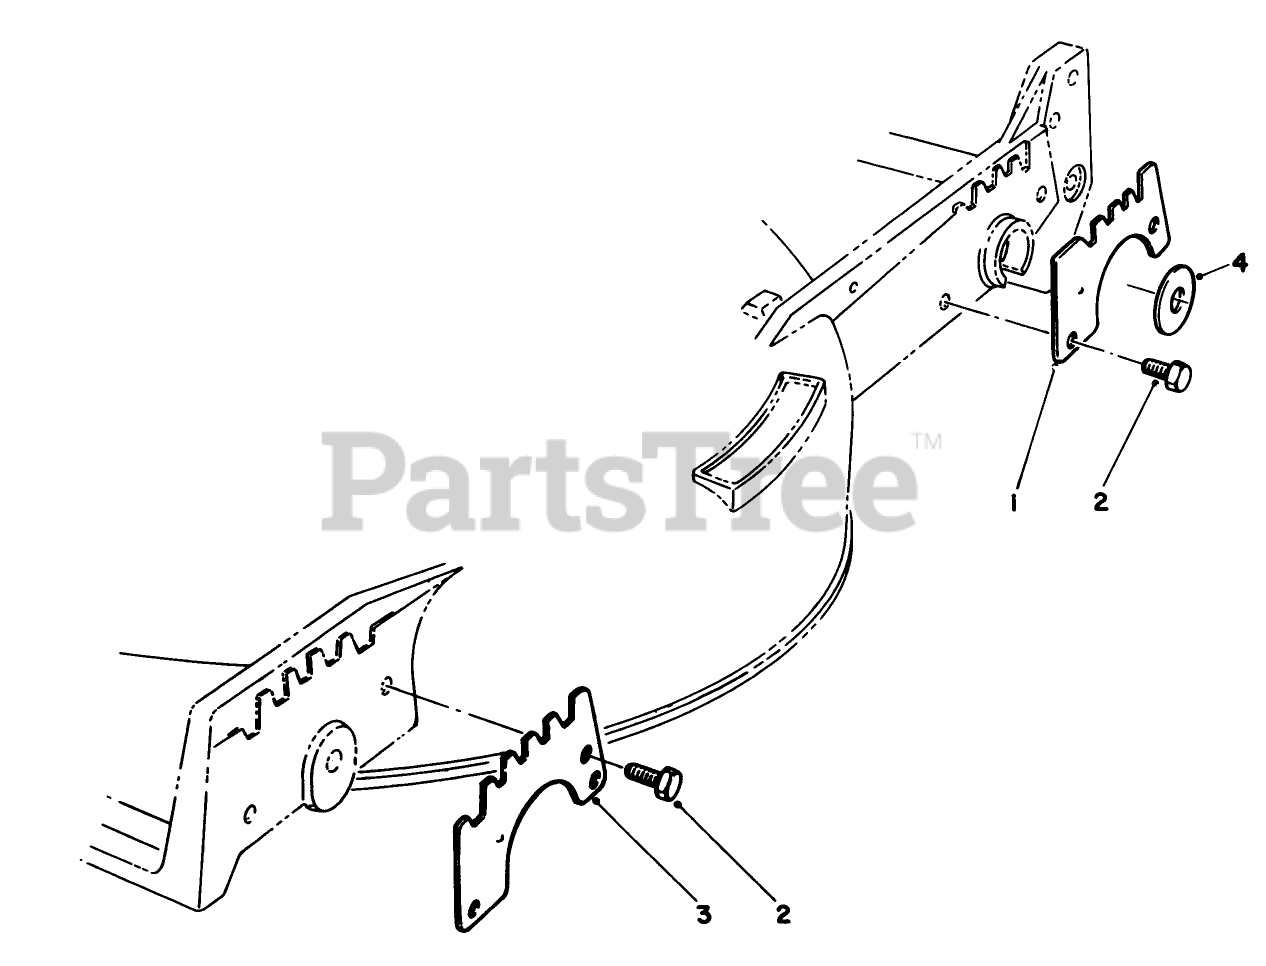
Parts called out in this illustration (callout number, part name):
1	WEAR PLATE,REAR
2	PART CAT OPC
3	WEAR PLATE
4	PIVOT WASHER
